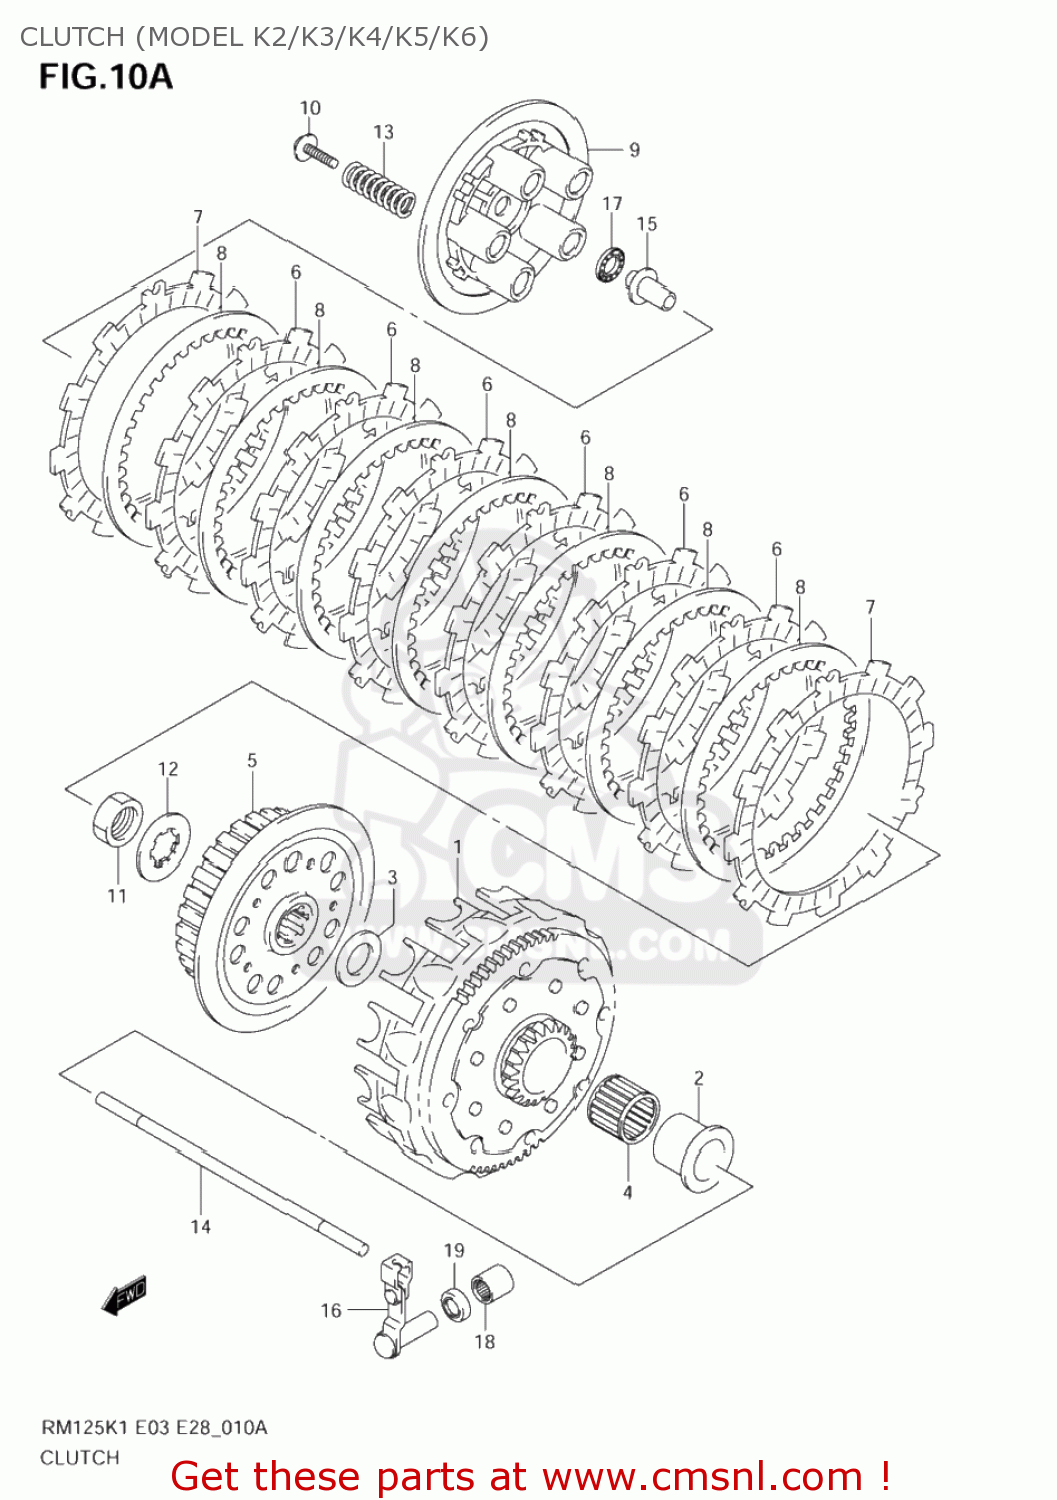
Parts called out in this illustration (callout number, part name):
1	GEAR ASSY,PRI DRIVEN
2	SPACER,PRIMARY DRIVEN GEAR
3	WASHER
4	BEARING(25X30X22)
5	HUB,CLUTCH SLEEVE
6	PLATE,CLUTCH DRIVE (NAS)
7	PLATE,CLUTCH DRIVE (NAS)
8	PLATE,CLUTCH DRIVEN(T:1.4) (NAS)
9	DISC,CLUTCH PRESSURE
10	BOLT(5X25)
11	NUT
12	WASHER,LOCK
13	SPRING
14	ROD,CLUTCH PUSH
15	PIECE,CLUTCH PUSH
16	CAMSHAFT,CLUTCH RELEASE
17	BEARING(10X22X2.8)
18	BEARING(10X14X15)
19	SEAL,OIL(10X17X5)
